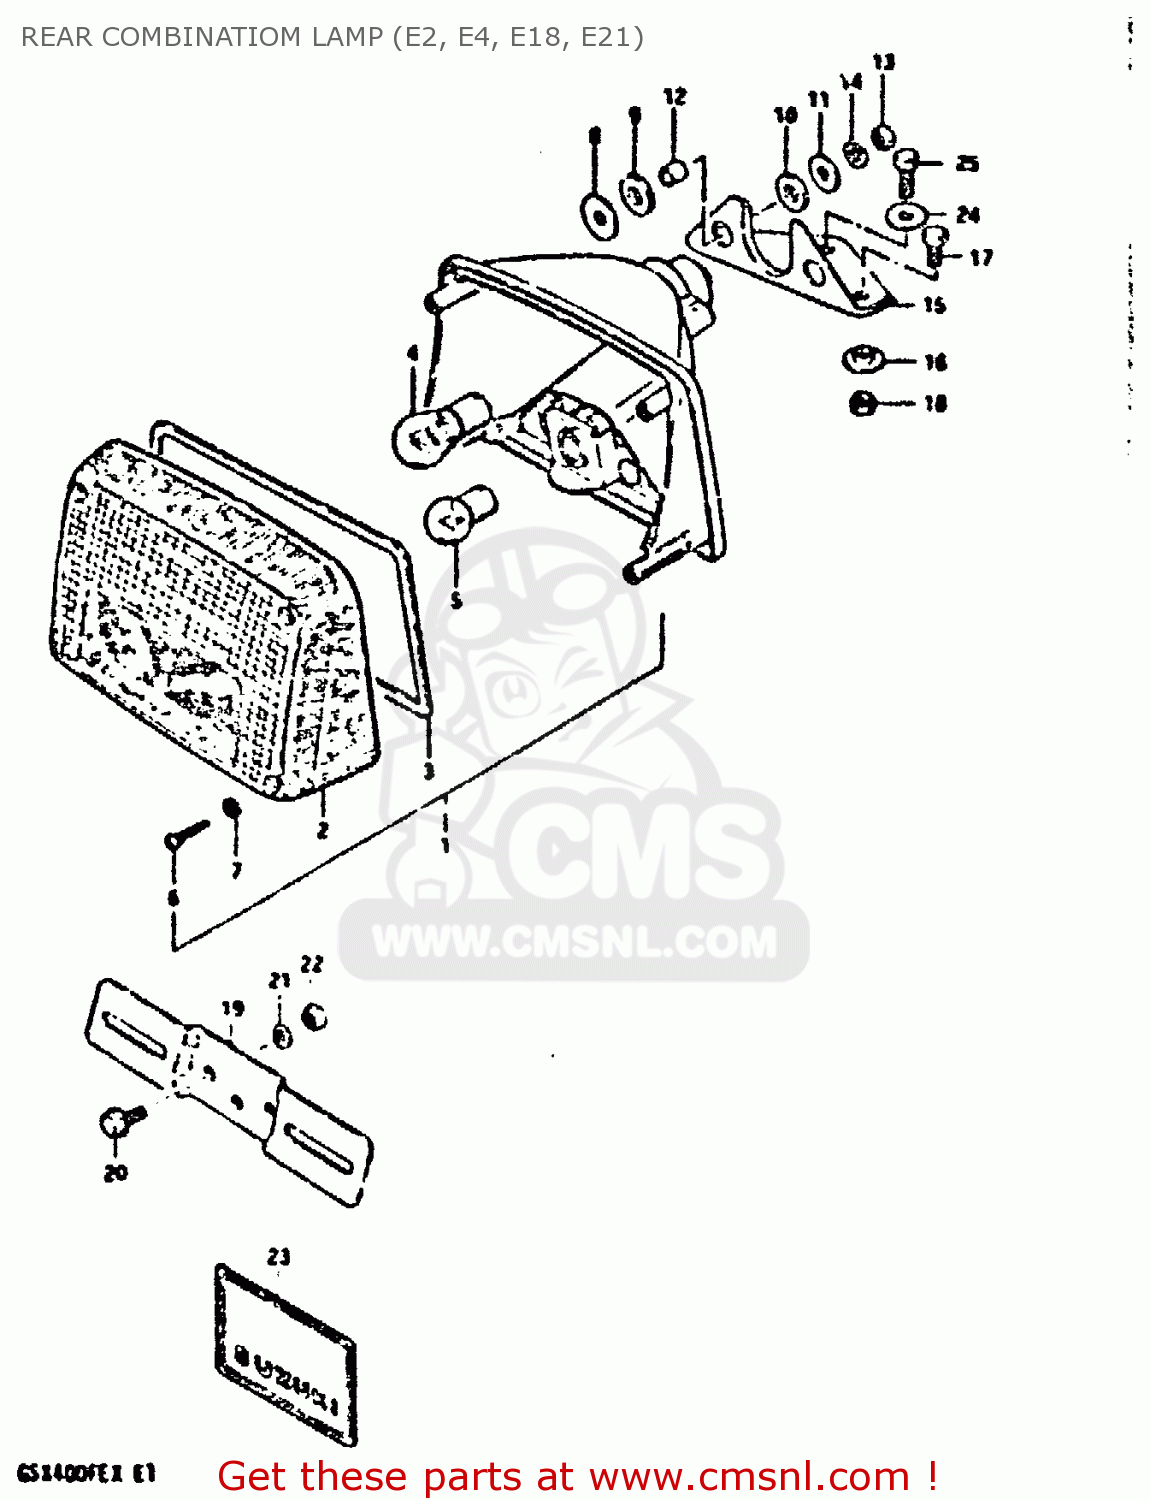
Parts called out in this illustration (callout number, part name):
1	LAMP, REAR COMBINATION
2	LENS
3	GASKET (NAS)
4	BULB 12V21/5W
5	BULB
6	SCREW,REAR COMBINATION LAMP
7	GASKET
8	WASHER
9	CUSHION
10	CUSHION
11	WASHER(6,5X22X1.6)
12	SPACER(6.1X9X7.5)
13	NUT
14	LOCK WASHER
15	BRACKET,RR COMBINATION LAMP
16	WASHER
17	BOLT, UPPER
18	NUT 6MM
19	BRACKET, LICENSE PLATE
20	BOLT
21	LOCK WASHER
22	NUT
23	EMBLEM, REAR
24	WASHER
25	BOLT
